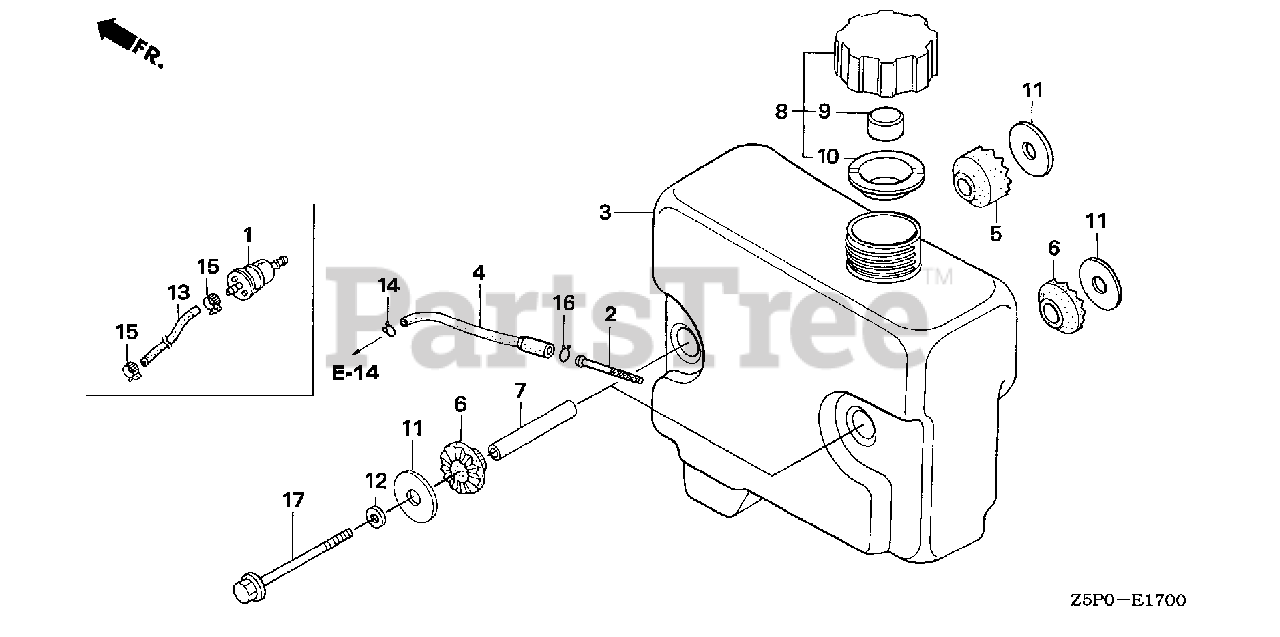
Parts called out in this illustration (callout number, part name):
2	FILTER, FUEL
3	TANK, FUEL
4	TUBE, FUEL
5	RUBBER B, TANK MOUNTING
6	RUBBER B, TANK MOUNTING
7	COLLAR, TANK SETTING
8	CAP ASSY., FUEL TANK
9	SPONGE, FUEL CAP BREATHER
10	GASKET, FUEL CAP
11	WASHER, TANK MOUNTING
12	WASHER, PLAIN (8MM)
14	CLIP, TUBE (B8)
16	CLIP, TUBE (C11)
17	BOLT, FLANGE (8X95)
